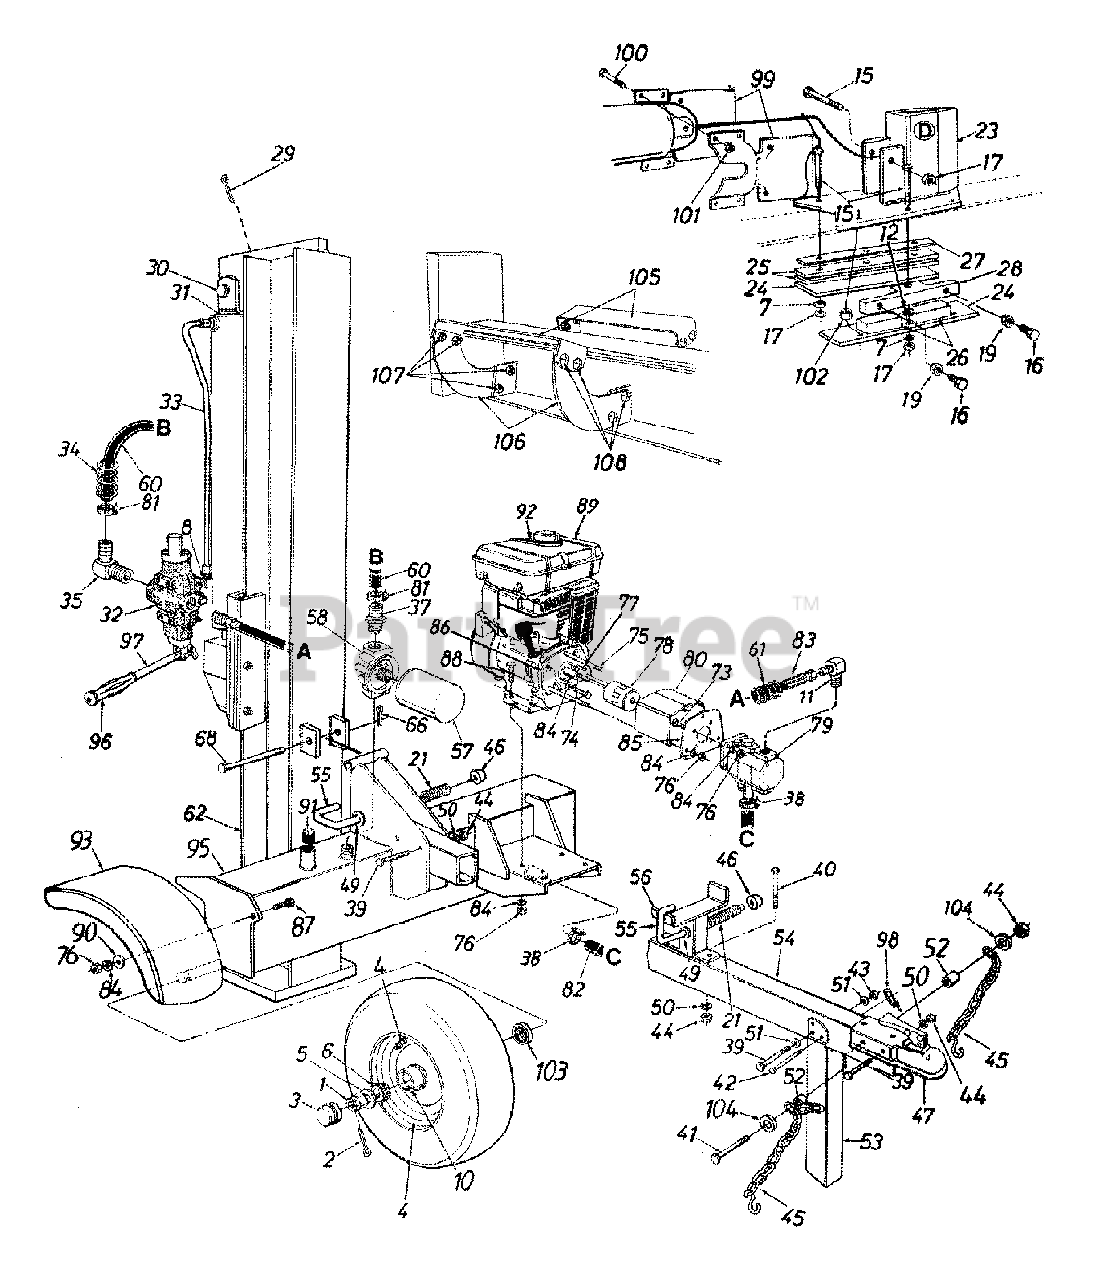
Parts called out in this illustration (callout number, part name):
1	Slotted Nut 3/4-16 Thd.
2	Cotter pin 5/32" Dia.
3	Hub Cap
4	Wheel Ass'y. Comp.
4	Tire Only
4	Rim Only
4	Air Valve Only
5	Fl-Wash. .76" I.D. x 1.5" O.D.
6	Bearing Cone
7	L-Wash. 1/2" I.D.
8	90° Solid Male Adaptor
10	Bearing Cup
11	90° Male Adapter
12	Fl-Wash. .531" I.D. x .94" O.D.
15	Hex Bolt 1/2-20 x 2.75" Lg. (Grade 8)
16	Hex Bolt 3/8-24 x 1.5" Lg.
17	Hex L-Nut 1/2-20 Thd.
19	Hex Jam Nut 3/8-24 Thd. (Grade 5)
21	Comp. Spring 4" Lg.
23	Wedge Ass'y.
27	Adjustable Gib Shim
29	Cotter Pin
30	Cylinder Mounting Pin
31	Hydraulic Cylinder
32	Control Valve
33	Metal Pressure Tube
34	Hose Guard
35	Return Elbow
37	3/4" Hose Barb.
38	Hose Clamp
39	Hex Bolt 3/8-16 x 3" Lg. (Grade 8)
40	Hex Bolt 3/8-16 x 4" Lg.
41	Hex Bolt 3/8-16 x 4.25" Lg. (Grade 5)
42	Clevis Pin 5/16 x 2.5" Lg.
43	Hex L-Nut 3/8-16 Thd.
44	Hex Nut 3/8-16 Thd.
45	Chain-Tow Hitch
46	Push Cap
47	Hitch Coupler
49	Fl-Wash. .635" I.D. x .93" O.D.
50	L-Wash. 3/8" I.D.
51	Fl-Wash. .406" I.D. x .75" O.D.
52	Spacer .44" Lg.
53	Jack Stand
54	Tongue Tube
55	Locking Rod
56	Beam Support Ass'y.
57	Filter Element
58	Filter Head
60	Return Hose 3/4" I.D. x 44" Lg.
61	Hose Guard
68	Hinge Pin 1/2 x 4.8" Lg.
73	Hex Bolt 5/16-24 x 1" Lg.
74	Hex Bolt 5/16-24 x .62" Lg.
75	Hex Bolt 5/16-24 x 4" Lg.
76	Hex Nut 5/16-24 Thd.
77	Sq.-Key 3/16" x .75"
78	Flexible Coupling
79	Gear Pump
80	Coupling Shield
81	Hose Clamp 5/8"
82	Suction Hose
83	High Pressure Hydraulic Hose 48"
84	L-Wash. 5/16" I.D.
85	Rear Coupling Support Brkt.
86	Front Coupling Support Brkt.
87	Hex Bolt 5/16-24 x .75" Lg.
88	Hex Bolt 5/16-24 x 1.75" Lg.
89	Engine
90	Fl-Wash. .344" I.D. x .875" O.D.
91	L-Vent Pipe Plug
92	Spark Plug Boot
93	Fender
95	Frame Weldment
97	Control Handle
98	Spring Pin
99	Dislodger
100	Hex Cap Scr. 3/8-16 x 2" Lg. (Grade 5)
101	Insert Lock Nut 3/8-16
102	Spacer 1/2" I.D. x 3/4" O.D. x .68" Lg.
103	Bearing Seal Only
104	Fl-Wash. 3/8" I.D. x .87" O.D.
105	Log Cradle
106	Cradle Support Brkt.
107	Flanged Lock Nut 3/8-16
108	Carriage Bolt 3/8-16 x 1" Lg.
